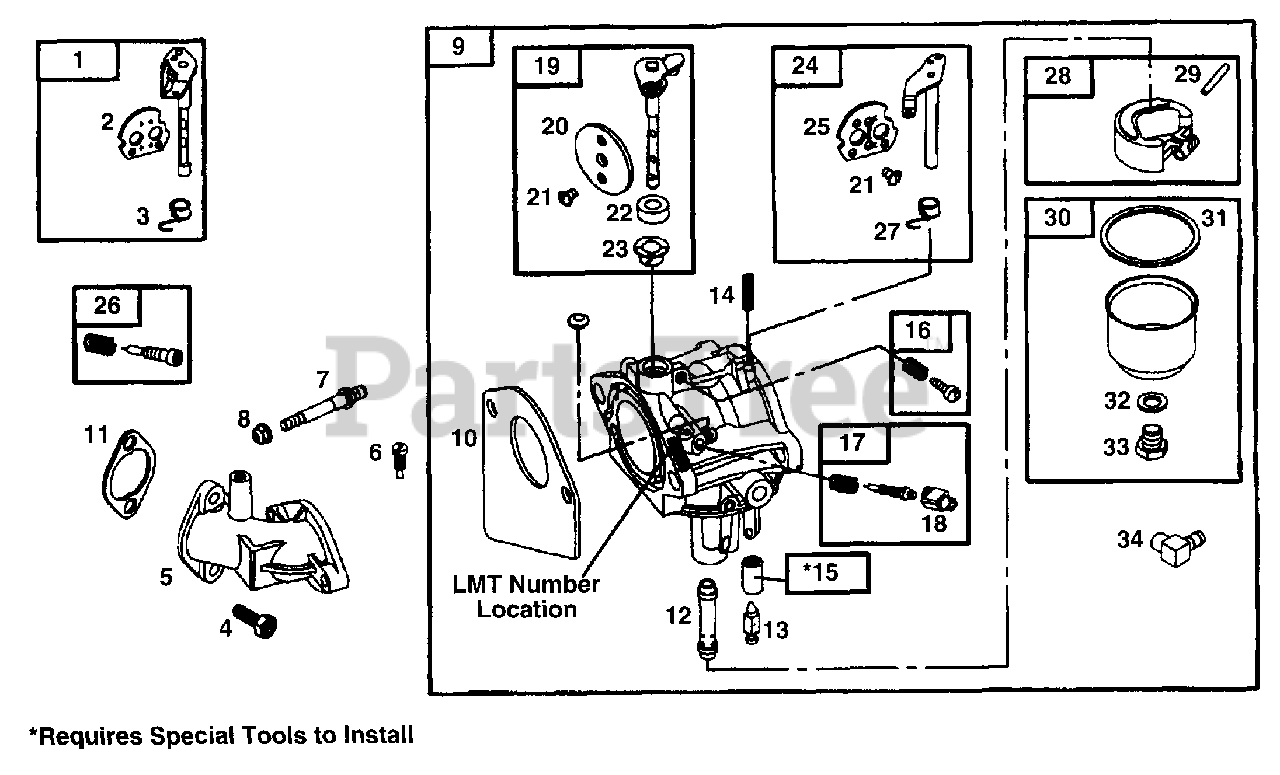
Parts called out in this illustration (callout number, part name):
1	Choke Shaft Kit (Choke A Matic)
2	Inlet Valve (Choke A Matic)
3	Spring & Seal Assy (Choke a Matic)
4	Hex Head Torx Screw, T-30
5	Intake Manifold
7	Hex Drive Stud
8	Hex Nut
9	Carburetor
10	Carburetor Gasket
11	Intake Gasket
12	Carb Nozzle
12	Nozzle / Jet Assy
13	Inlet Valve
14	Lever Spring
15	Inlet Seat, (Gravity Feed)
16	Idle Speed Screw
17	Idle Mixture Kit
18	Limiter Cap
19	Throttle Shaft Kit
20	Throttle Valve
21	Round Washer Screw
22	Throttle Shaft Seal
23	Throttle Shaft Bushing
24	Choke Shaft Kit,
25	Choke Valve (Manual Choke)
26	Idle Mixture Kit
27	Spring & Seal Assy (Manual Choke)
28	Carburetor Float
29	Float Hinge Pin
30	Float Bowl
31	Float Bowl Gasket
32	Seal Washer
33	Hex Head Screw
34	Hose Connector
